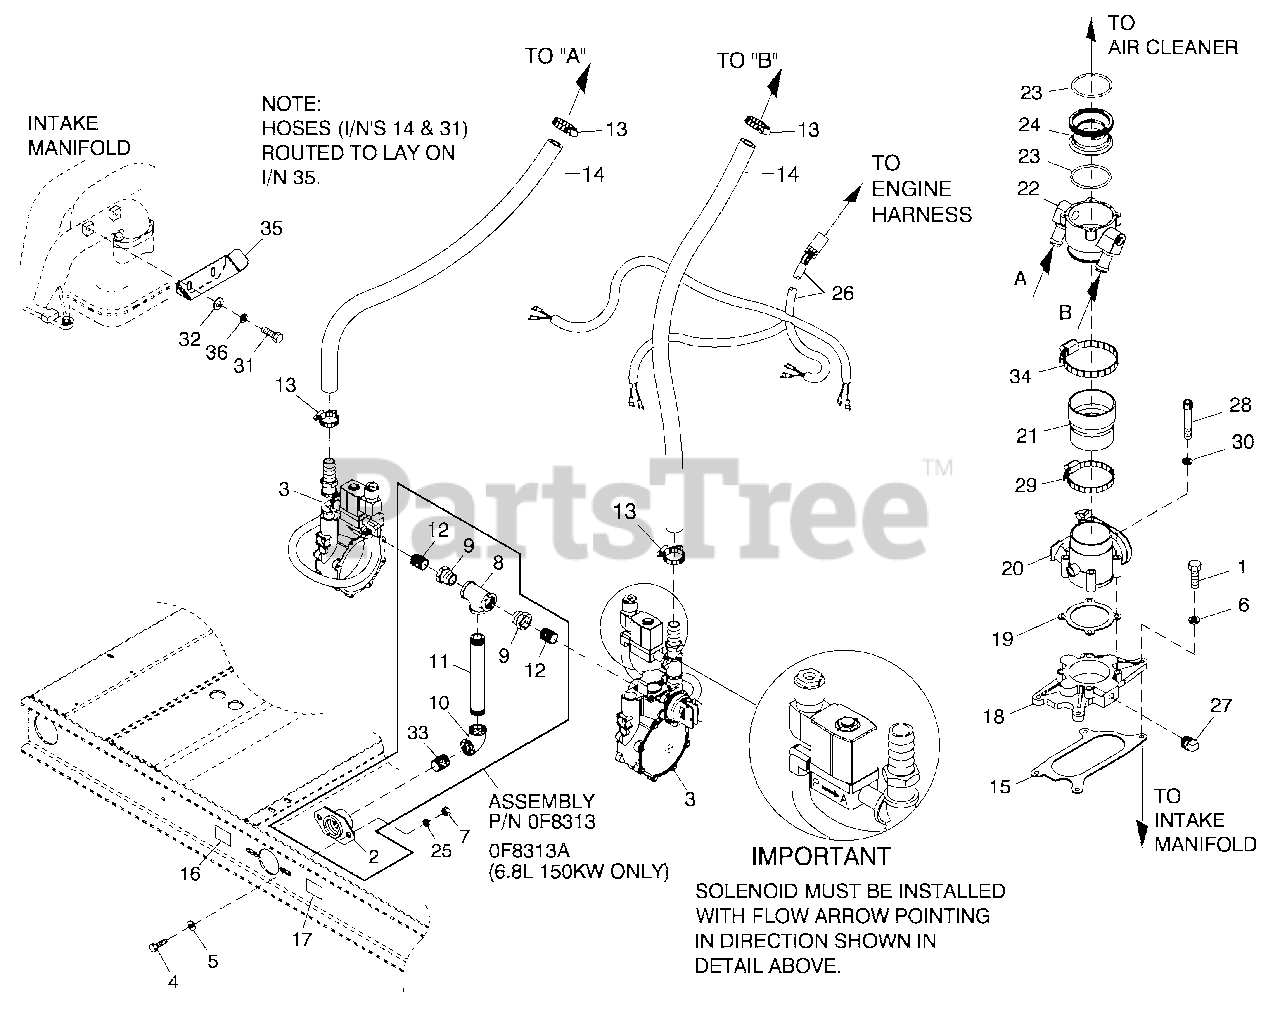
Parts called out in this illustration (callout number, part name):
1	SCREW HHC 5/16-18 X 1-1/4 G5
2	SUPPORT NAT GAS SOLENOID
3	REG ASSY 6.8L 130 KW DUAL LP QT
4	SCREW HHC M12-1.75 X 20 G8.8
5	WASHER FLAT 1/2 ZINC
6	WASHER LOCK M8-5/16
7	NUT HEX M12-1.75 G8 YEL CHR
8	PIPE TEE 1-1/4 NPT
9	BSHG RDCR HEX1-1/4-3/4
10	ELBOW 90D1-1/4 NPT
11	NIPPLE PIPE 1-1/4 NPT X 3 (100 KW & 130 KW)
12	NIPPLE CLOSE 3/4X1.375
13	CLAMP HOSE #10 .56-1.06
14	HOSE 3/4 ID SAE-30R2 (45" LG)
15	GASKET ADAPTER THROT BODY
16	DECAL INLET PRESSURE
17	DECAL FUEL INLET LPG
18	ADAPTOR THROTTLE BODY
19	GASKET GOVERNOR ACTUATOR
20	ACTUATOR BOSCH 60 GOVERNOR
21	REDUCER 3.0" TO 2.75" TURBO
22	MIXER 40/60MM ACTUATOR ASSY
23	RING 2-3/4X3/32X2-15/16
24	VENTURI THROTTLE 42MM (6.8L 100 KW)
25	WASHER LOCK 1/2
26	HARNESS, FUEL JUMPER DUAL REG
27	PLUG STD PIPE 1/4 STEEL SQ HD
28	SCREW SHC M6-1.0 X 45 G12.9
29	CLAMP HOSE #44 2.31-3.25
30	WASHER LOCK M6-1/4
31	SCREW HHC M6-1.0X 20 G8.8
32	WASHER FLAT M6
33	NIPPLE CLOSE 1.25 NPT X 1.625
34	CLAMP HOSE #52 2.81-3.75
35	BRAC KET, HOSE RISER
36	WASHER LOCK M6-1/4
